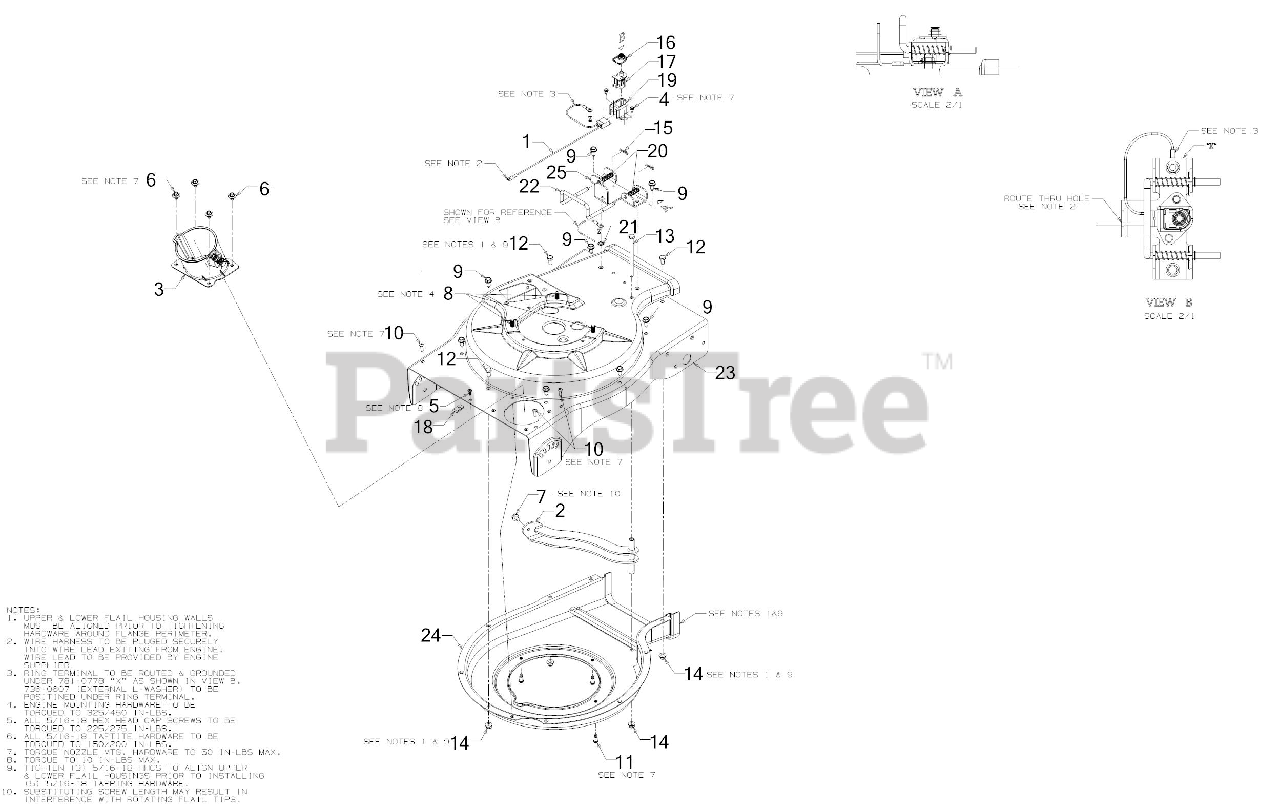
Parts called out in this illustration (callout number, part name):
1	WIRE HARNESS ASSEMBLY
2	SCREEN ASSEMBLY
3	HOSE ADAPTER BASE ASSEMBLY
4	HEX SCREW AB-TAP #10-16 x 0.500
5	SCREW #10-16 x 0.500
6	SCREW 1/4-20 x .50
7	SCREW 5/16-18 x .500
8	SCREW 3/8-16 x 1
9	SCREW 5/16-12 x .750
10	SCREW #12-16 x .750
11	SCREW .30 x .46
12	SCREW 5/16-18X .625 GR5
13	SCREW 5/16-18 x 4.5 GR5
14	FLANGE LOCK NUT 5/16-18
15	COTTER PIN .072 DIA
16	SWITCH COVER
17	SNAP MOUNT SWITCH
18	U-TYPE SPEED NUT
19	SWITCH COVER
20	COMPRESSION SPRING
25	MOUNTING BRACKET
